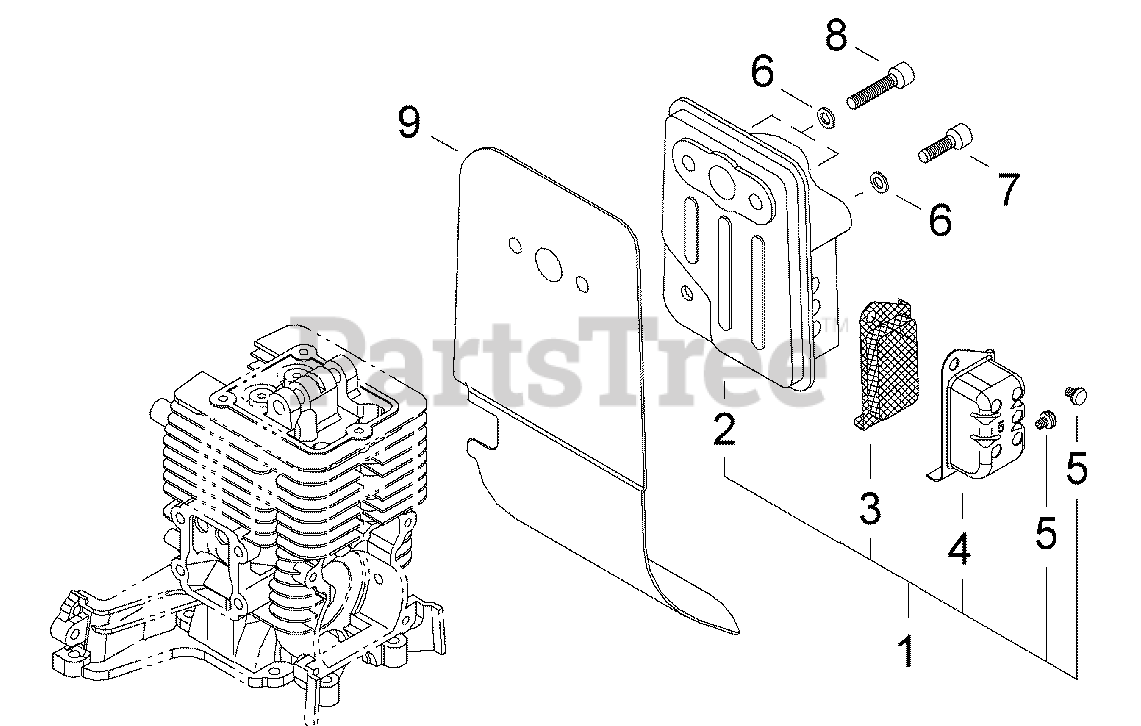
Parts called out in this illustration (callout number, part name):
1	MUFFLER ASSY
2	MUFFLER
3	SCREEN, SPARK ARRESTOR
4	GUIDE, EXHAUST
5	SCREW - 4X6
6	WASHER - 5
7	SCREW - 5X16
8	SCREW - 5X25
9	SHIELD, EXHAUST
